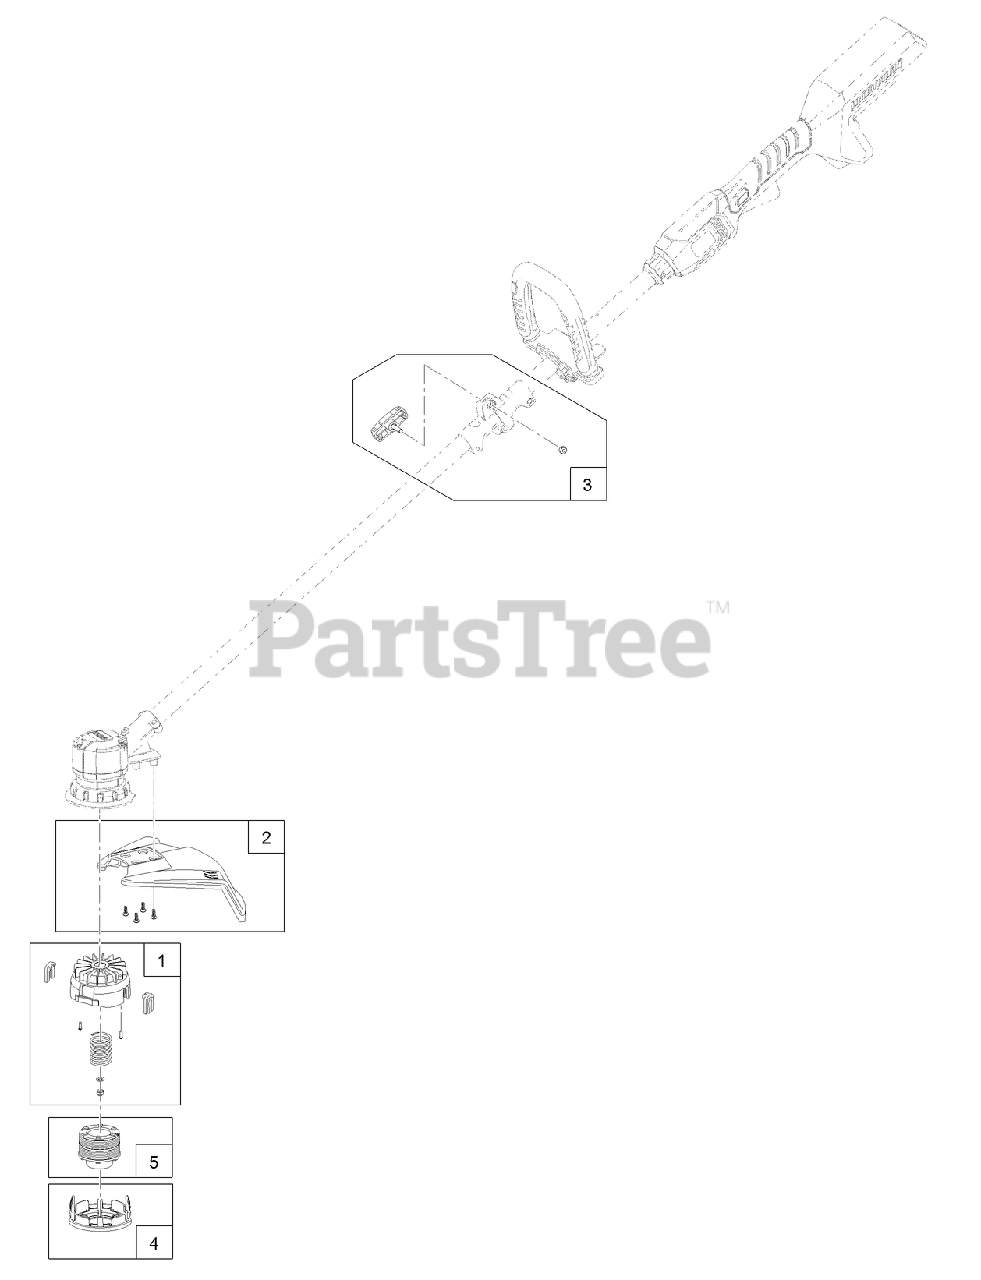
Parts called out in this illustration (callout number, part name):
1	HEAD-FEED, BUMP
2	GRASS SHIELD ASM
3	SHAFT CONNECTION HARDWARE KIT
4	RETAINER-CAP, SPOOL
5	3-PK DUAL-LINE SPOOL
